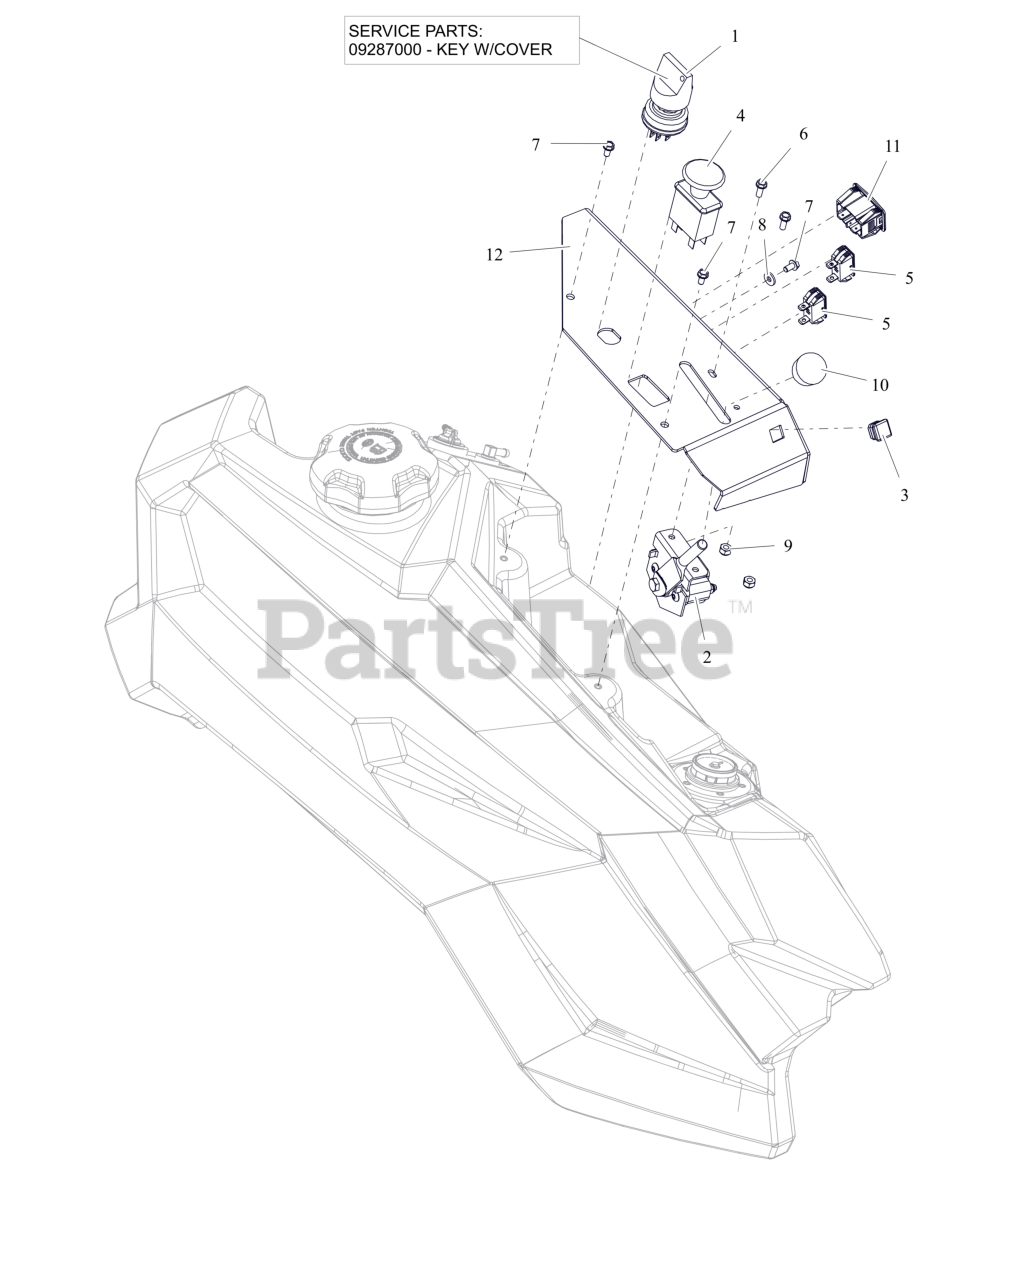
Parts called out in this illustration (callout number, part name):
1	SWITCH, IGNITION
1	KEY, W/ SHIELD
2	CONTROL, ELECTRONIC THROTTLE
3	PLUG, 5/8" SQ BLACK (14-20GA)
4	SWITCH, CLUTCH
5	LIGHT, INDICATOR (RED)
6	BLT, HWH #10-24X.50 ZCC
7	SCR-MCH 10-24X.38 HWHSTAINLESS
8	WSHR-FL-STL .196X.50X.06 ZC120
9	NUT-LK-NYL #10-24 G2 ZCC
10	KNOB-CONTROL-BLACK .38-16X.50
11	HOUR METER
12	PANEL- RH CONTROL (RED)
